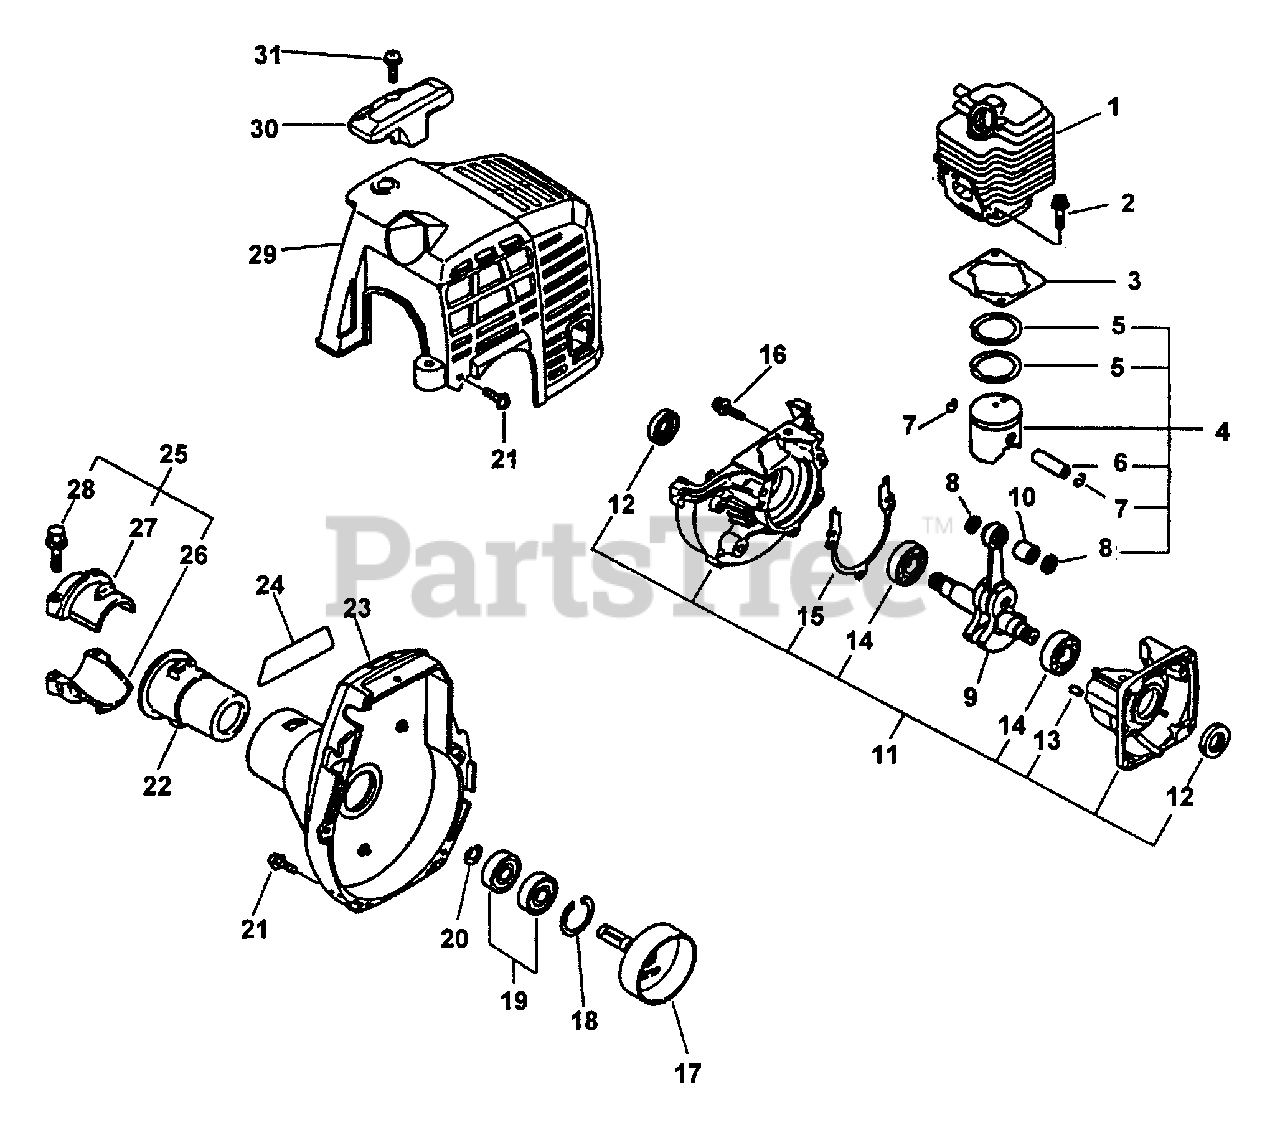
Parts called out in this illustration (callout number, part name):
1	CYLINDER
2	SCREW - 5X22
3	GASKET, CYLINDER
4	PISTON KIT
5	RING, PISTON
6	PIN, PISTON
7	RING, RETAINING
8	SPACER, PISTON
9	CRANKSHAFT ASSY
10	BEARING, NEEDLE
11	CRANKCASE KIT
12	SEAL, OIL
13	PIN - LOCATING
14	BEARING, BALL - 6201
15	GASKET, CRANKCASE
16	SCREW - 5X28
17	DRUM, CLUTCH
18	RING, RETAINING - 28
19	BEARING, BALL - 6001
20	RING, RETAINING - 12
21	SCREW - 4X16
22	CUSHION
23	FAN CASE ASSY
23	CASE, FAN
24	LABEL - MODEL PE-2400
25	HOLDER KIT
25	MAIN PIPE CLAMP KIT
26	CLAMP, MAIN PIPE
26	CLAMP, MAIN PIPE - LOWER
27	CLAMP, MAIN PIPE - UPPER
28	BOLT - 5X25
29	COVER, ENGINE
30	GUARD - TOP
31	SCREW - 5X16
